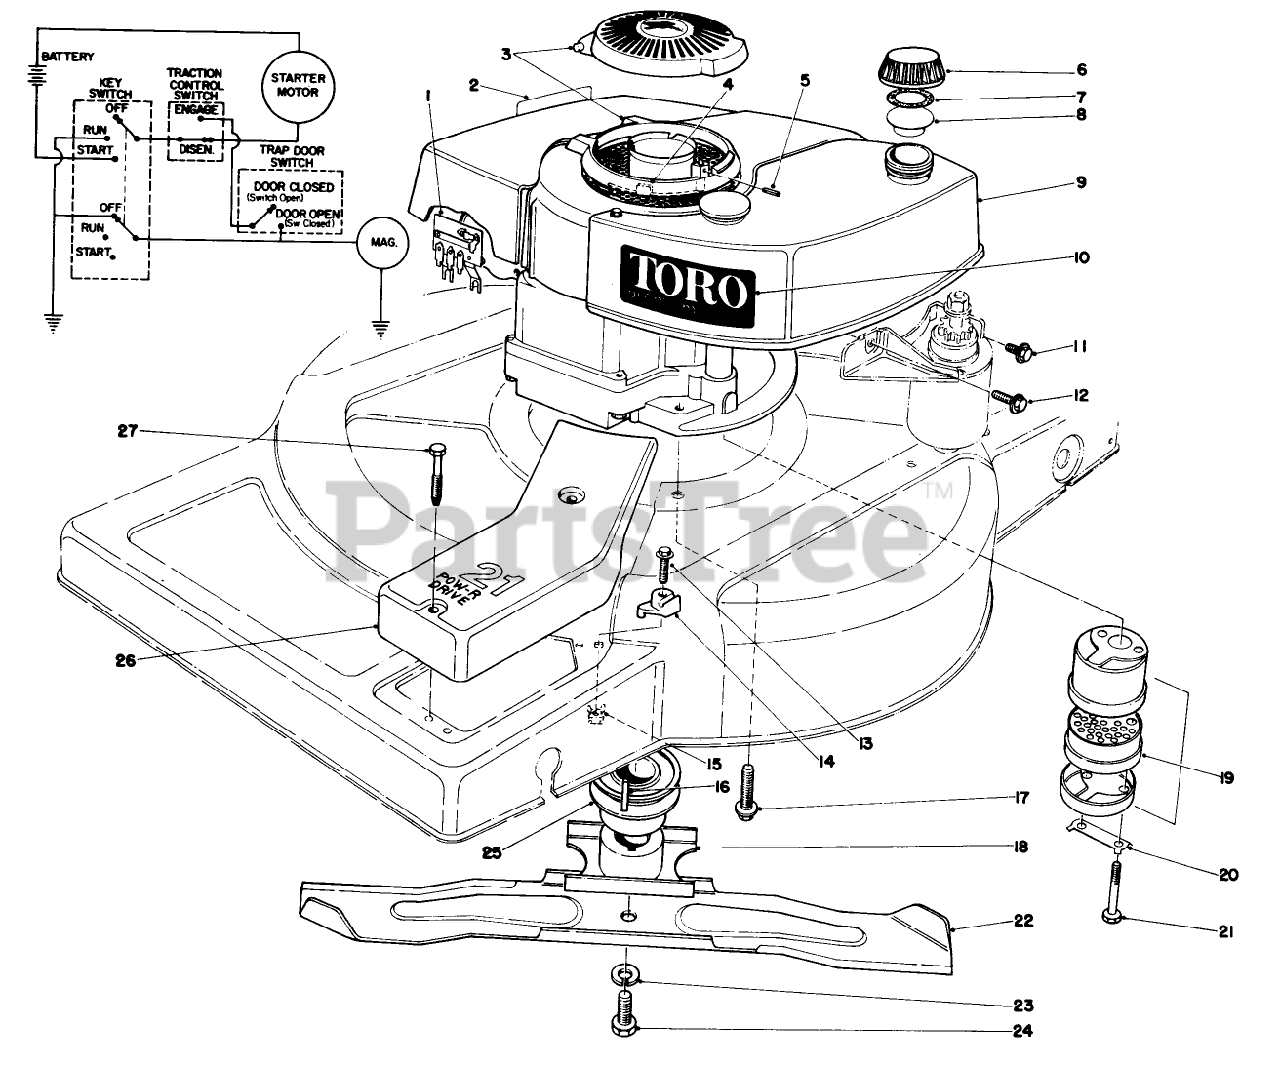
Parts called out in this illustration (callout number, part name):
5	SPRING PIN
7	GASKET
9	Engine (Model No. TNT100-10073C)
11	SCREW
16	KEY-SQUARE
19	MUFFLER ASM
20	CLIP - LOCKING
21	SCREW-HH
23	WASHER-LOCK
24	BLADE SCREW
27	SCREW-HWH
